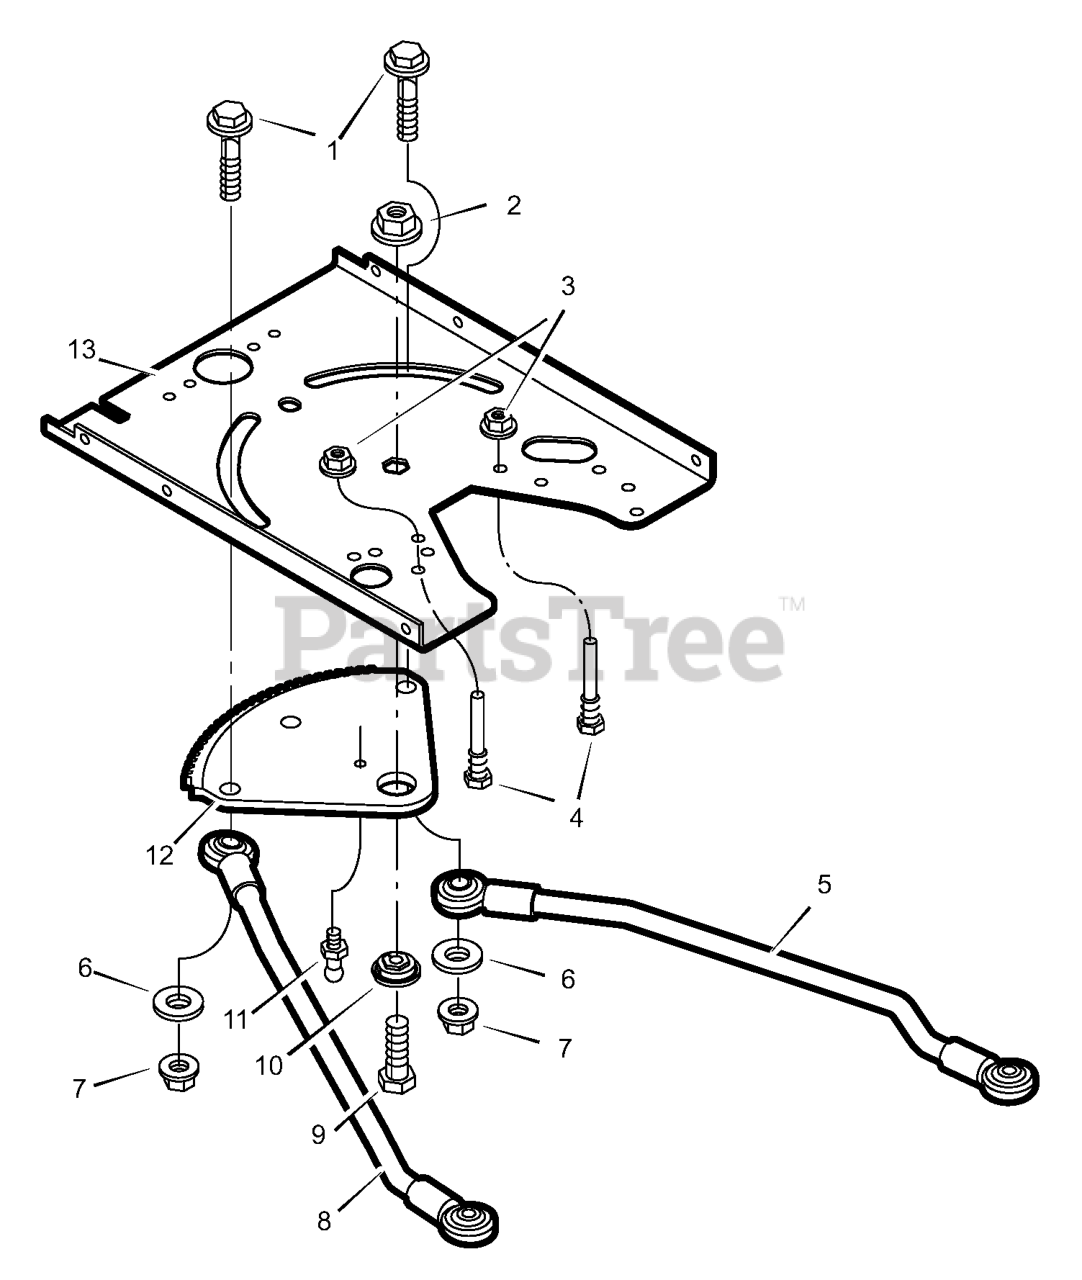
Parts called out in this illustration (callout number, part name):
1	Bolt, Shoulder
2	Nut, Lock
3	Nut, Flange
4	Guide, Screw
5	Link, Left Drag
7	Nut, Flange
8	Link, Right Drag
9	CAPSCREW, Hex Head, 5/16-18 x 1
10	Bearing, Sector Gear
11	Fitting, Lub
12	Gear, Sector
13	Plate, Steering
